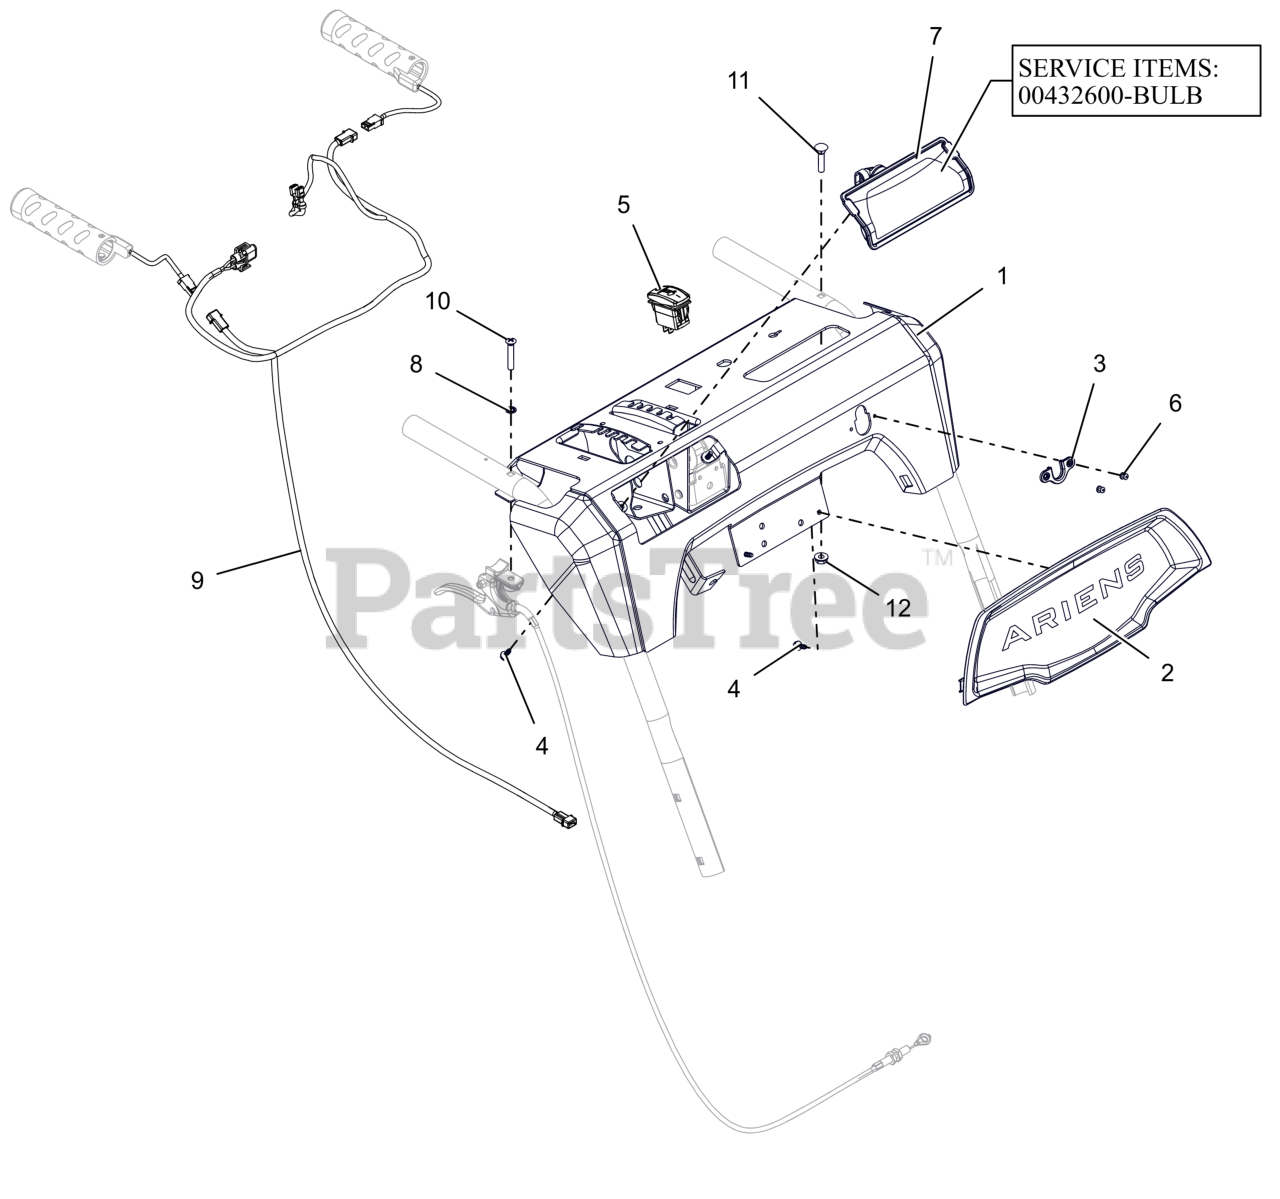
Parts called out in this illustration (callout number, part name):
1	CONTROL PANEL W/DECAL FRIC-TRK
2	BEZEL, DASH - ARIENS LG DASH
3	GROMMET, CABLE, QUICK TURN 2
4	SCR, PLASTIC #10X.50
5	SWITCH,ROCKER SPST-ON/OFF
6	RVT-POP #43 .125X.313 STL ZINC
7	HEADLIGHT ASY, HALO 20W 2SHOT
7	BULB, LIGHT-HALOGEN 20W
8	WSHR-LK-INT .250 TH TYA
9	HARNESS, LIGHT & WARMER
10	SCR,OVAL .25-20X1.50 ZCC
11	BLT-RDHDXLSQNK.25-20X1.25 G5ZC
12	NUT-LK-CTR-FLG .25-20 ZC120
